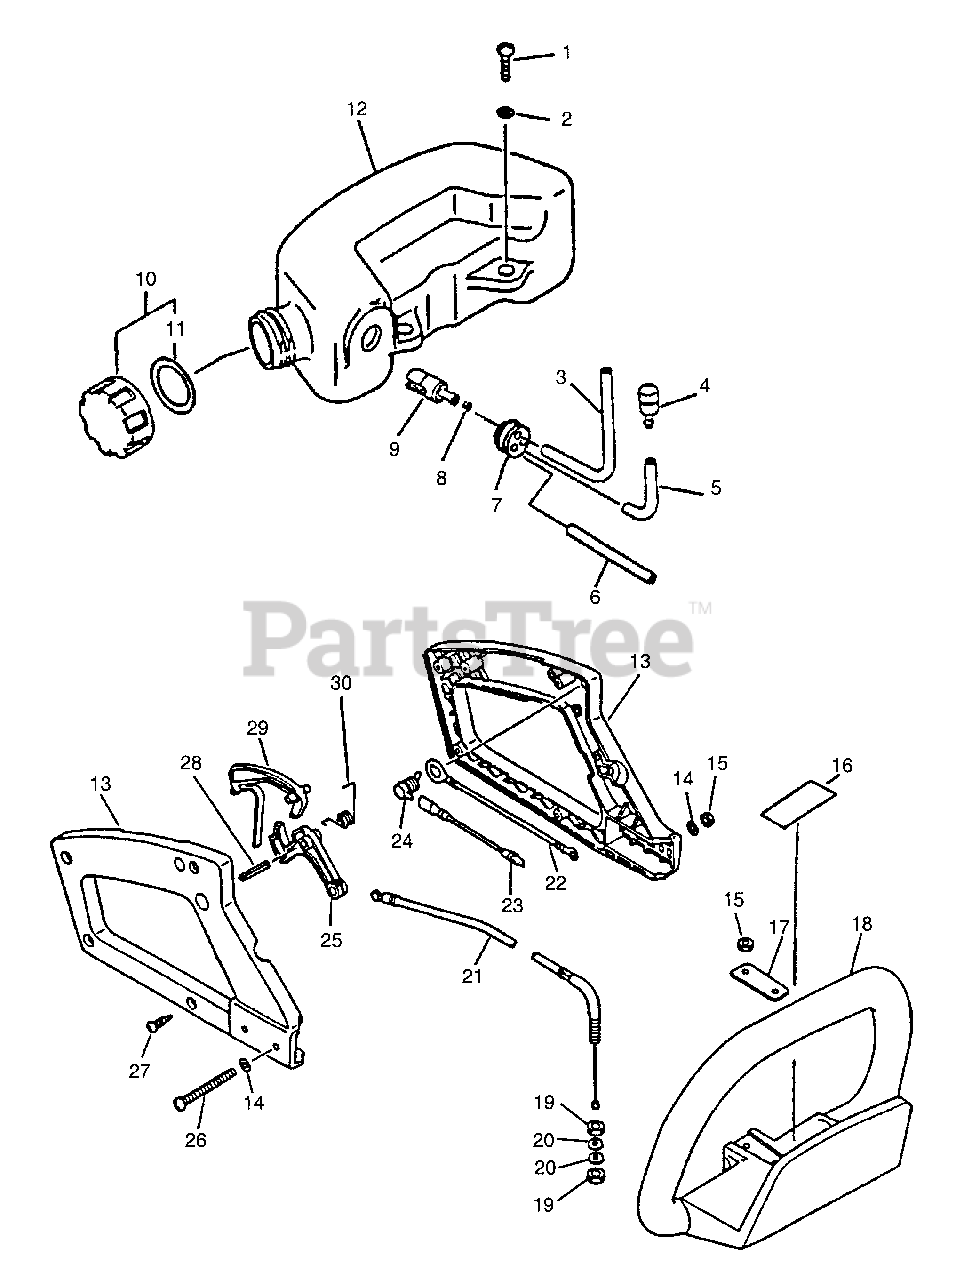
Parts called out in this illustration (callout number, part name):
1	SCREW - 5X16
2	WASHER - 5
3	PIPE - 3X5X195 -- BLACK
4	VENT, FUEL TANK
5	PIPE - 3X6X70 -- CLEAR
6	PIPE - 3X6X110 -- CLEAR
7	GROMMET
8	CLIP - 6
9	FILTER, FUEL
10	CAP ASSY
11	GASKET, CAP
12	TANK, FUEL
13	HANDLE ASSY - REAR
14	WASHER - 5
15	LOCKNUT - 5
16	LABEL - CAUTION
18	HANDLE - FRONT
20	WASHER - 6
21	CABLE, THROTTLE
22	LEAD - GROUND
23	LEAD - GROUND
24	IGNITION SWITCH ASSY
25	TRIGGER, THROTTLE
26	SCREW - 5X40
27	SCREW - 4X16
28	PIN - SPRING -- 5X25
29	LOCKOUT, THROTTLE
30	SPRING, TRIGGER
